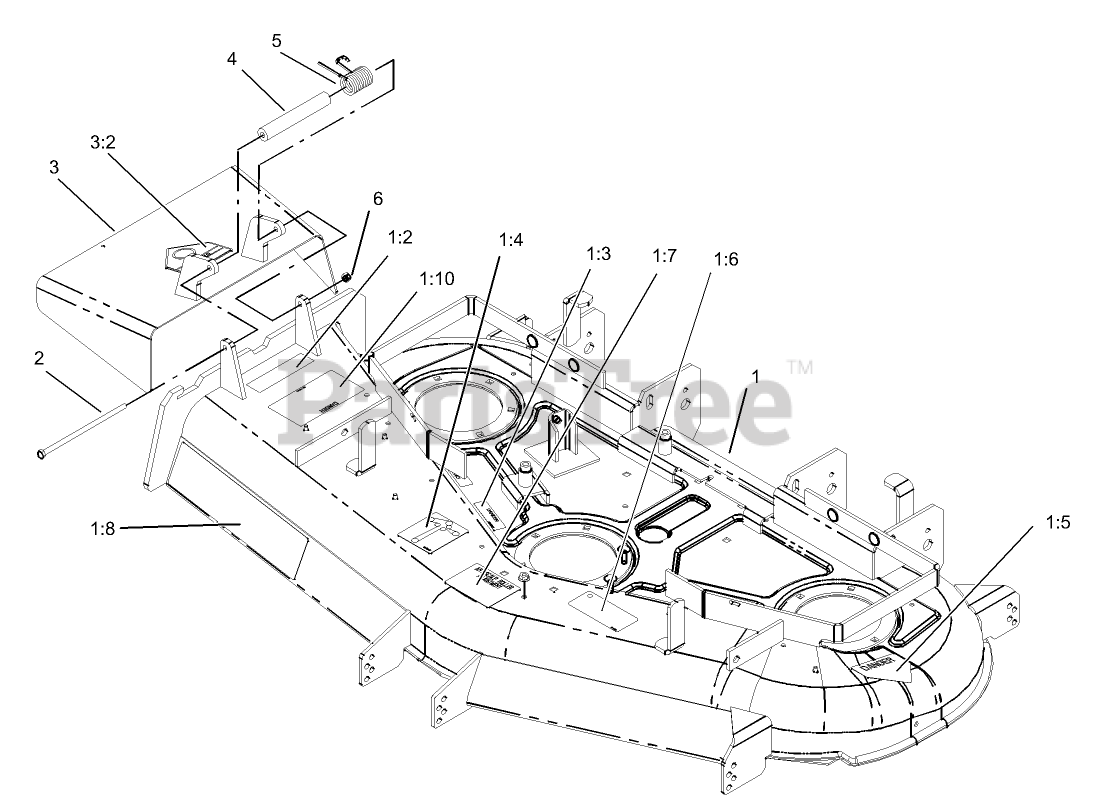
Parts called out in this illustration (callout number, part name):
1	Deck ASM
1:2	DECAL-WARNING
1:3	DECAL-COVER, MISSING
1:4	DECAL-ROUTING, BELT
1:5	DECAL-DANGER
1:6	DECAL-TORQUE, BLADE BOLT
1:7	DECAL-WHEEL, GAGE
1:8	DECAL
1:10	DECAL-DANGER, THROWN OBJECT
2	SCREW-HH
3	Deflector ASM
3:2	DECAL-DANGER
4	SPACER
5	SPRING-TORSION
6	NUT-LOCK, NI
